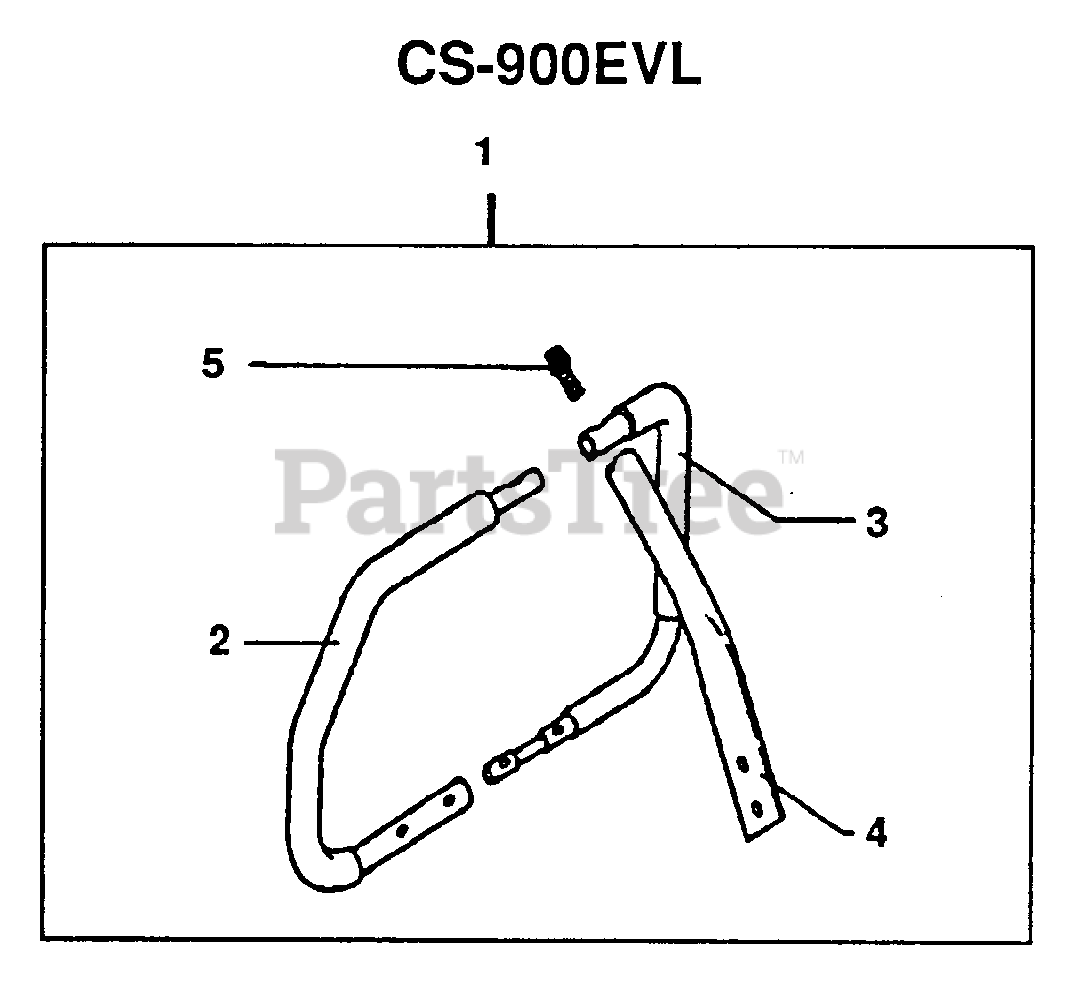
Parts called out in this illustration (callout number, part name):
1	HANDLE KIT
2	HANDLE - LEFT
3	HANDLE - RIGHT
5	BOLT 5×20
